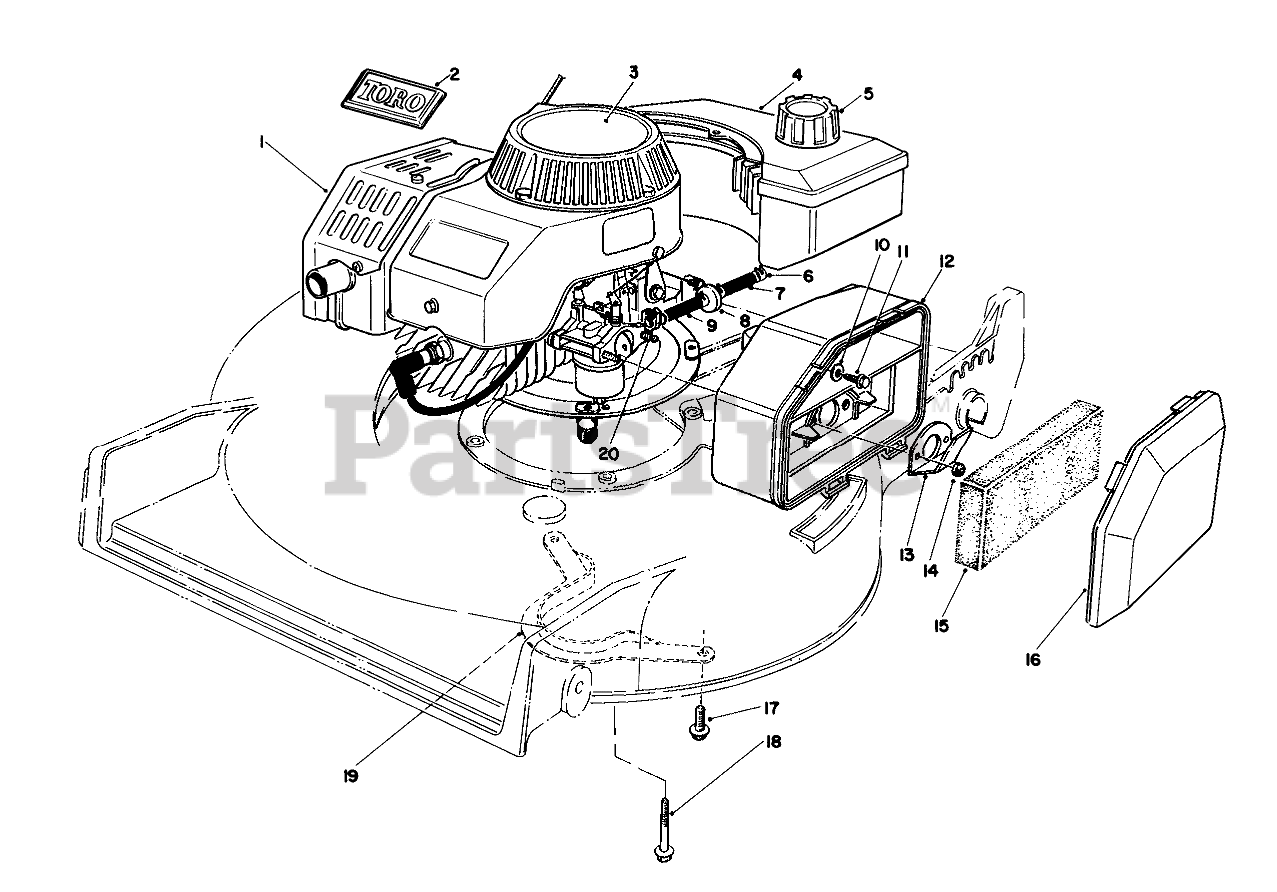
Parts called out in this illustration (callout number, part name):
1	Engine
2	TORO LOGO PLT
3	DECAL
4	Gas Tank Assembly
5	GAS CAP ASM
6	CLAMP-FUEL LINE
7	HOSE-FUEL
8	FILTER-FUEL
9	HOSE-FUEL
10	WASHER-FLAT
11	SCREW-HH
12	AIR CLEANER
13	SPIT BACK DEFLECTOR
14	NUT-LOCK
15	FILTER
16	AIR CLEANER COVER
17	SCREW-HWHTF
18	SCREW-HHF
19	BBC BELT GUIDE
20	FUEL LINE CLAMP
